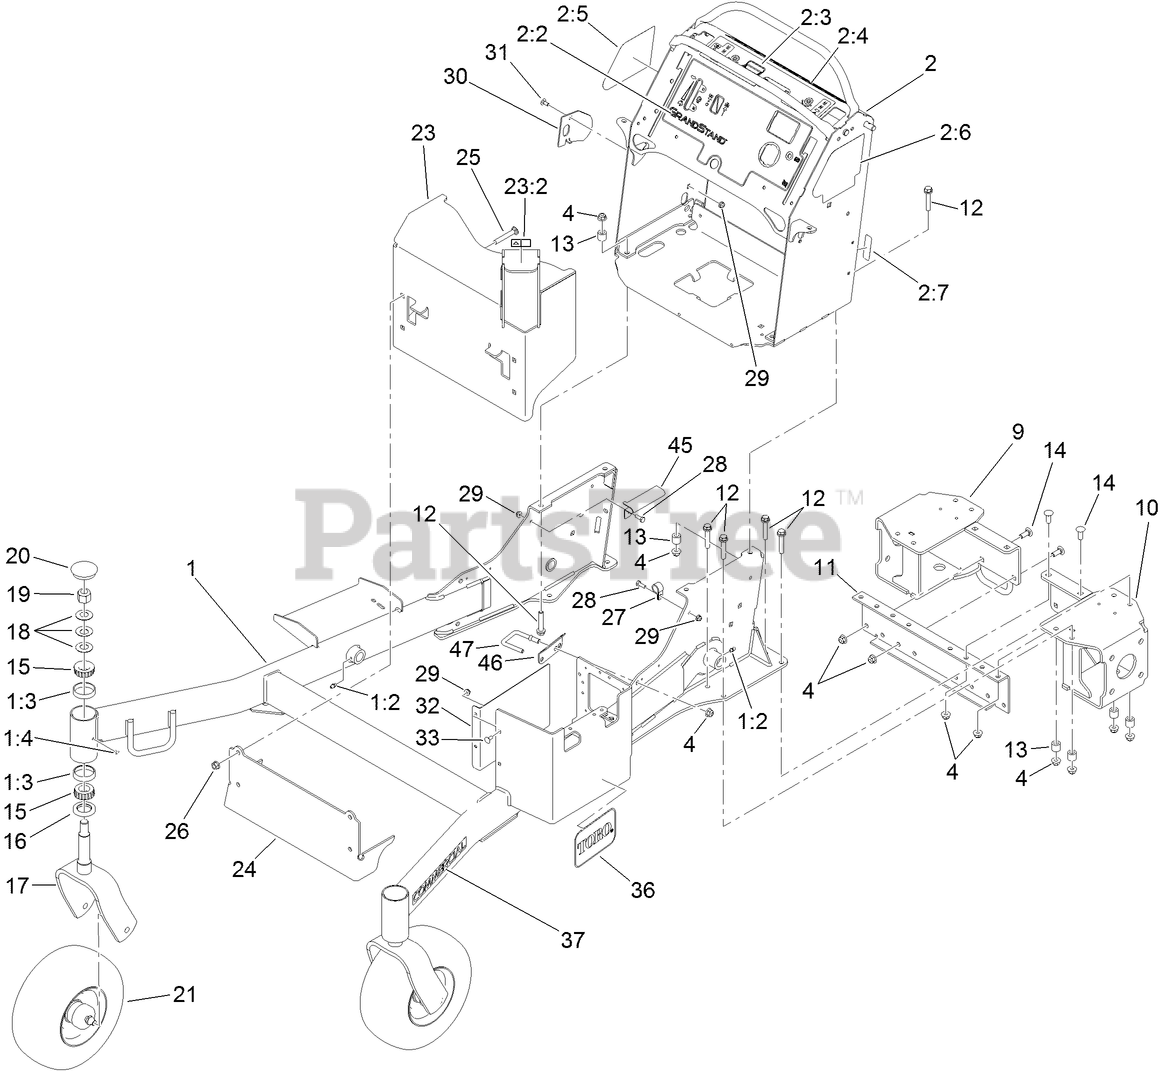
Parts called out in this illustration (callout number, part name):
1	FRONT FRAME ASM
1:2	FITTING-GREASE
1:3	CUP-BEARING
2	CONTROL TOWER ASM
2:2	DECAL-CONTROL PANEL, EFI
2:3	DECAL-OPC
2:4	DECAL-WARNING
2:5	DECAL-HOC
2:6	DECAL-SERVICE/SPARK ARREST
2:7	DECAL-FUSE
4	NUT-HF, NI
9	MOUNT-MOTOR, RH
10	MOUNT-MOTOR, LH
11	MOUNT-MOTOR, CENTER
12	SCREW-HHF
13	SPACER
14	SCREW-CARR
15	BEARING-ROLLER, TAPERED
16	SEAL-GREASE
17	FORK-CASTER
18	WASHER-BELLVILLE
19	NUT-LOCK, NI
20	CAP-GREASE
21	WHEEL/TIRE AND BEARING ASM
23	MUFFLER GUARD ASM
23:2	DECAL-WARNING
24	PANEL-GUARD
25	SCREW-CARR
26	NUT-HF
27	CLAMP-CABLE
28	SCREW-HH
29	NUT-HF
30	PLATE-STRIKER
31	SCREW-CARR
32	SHIELD-HEAT
33	SCREW-CARR
36	DECAL
37	DECAL-COMMERCIAL
45	BRACKET-HOSE, FUEL (DOUBLE)
46	GUARD-HOSE
47	GUIDE-HOSE
